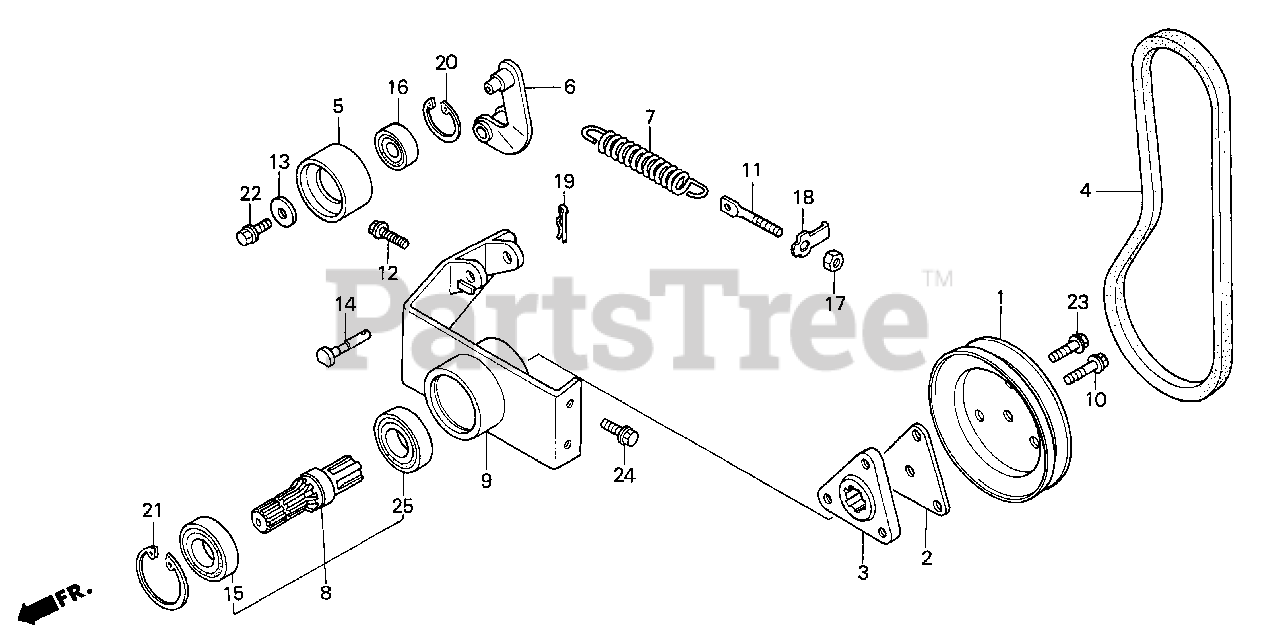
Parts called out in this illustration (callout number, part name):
1	PULLEY, DRIVEN
2	PATCH, PULLEY
3	BOSS, DRIVEN PULLEY
4	V-BELT (LB-33)
5	ROLLER, TENSION
6	ARM, TENSIONER
7	SPRING, BELT TENSIONER
8	SHAFT, FR. P.T.O.
9	BRACKET, FR. P.T.O.
10	BOLT, FLANGE (8X20)
11	BOLT, ADJUSTING
12	BOLT (8X20)
13	WASHER (6MM)
14	PIN, FR. P.T.O.
15	BEARING, RADIAL BALL (28X52X12)
16	BEARING, RADIAL BALL (6202G)
17	NUT, HEX. (8MM)
18	WASHER C, TONGUED (NOT AVAILABLE)
19	PIN, LOCK (12MM)
20	CIRCLIP (INNER) (35MM)
21	CIRCLIP (INNER) (52MM)
22	BOLT, FLANGE (6X16)
23	BOLT, FLANGE (8X16)
24	BOLT, FLANGE (8X18)
25	BEARING, RADIAL BALL (6205UU)
